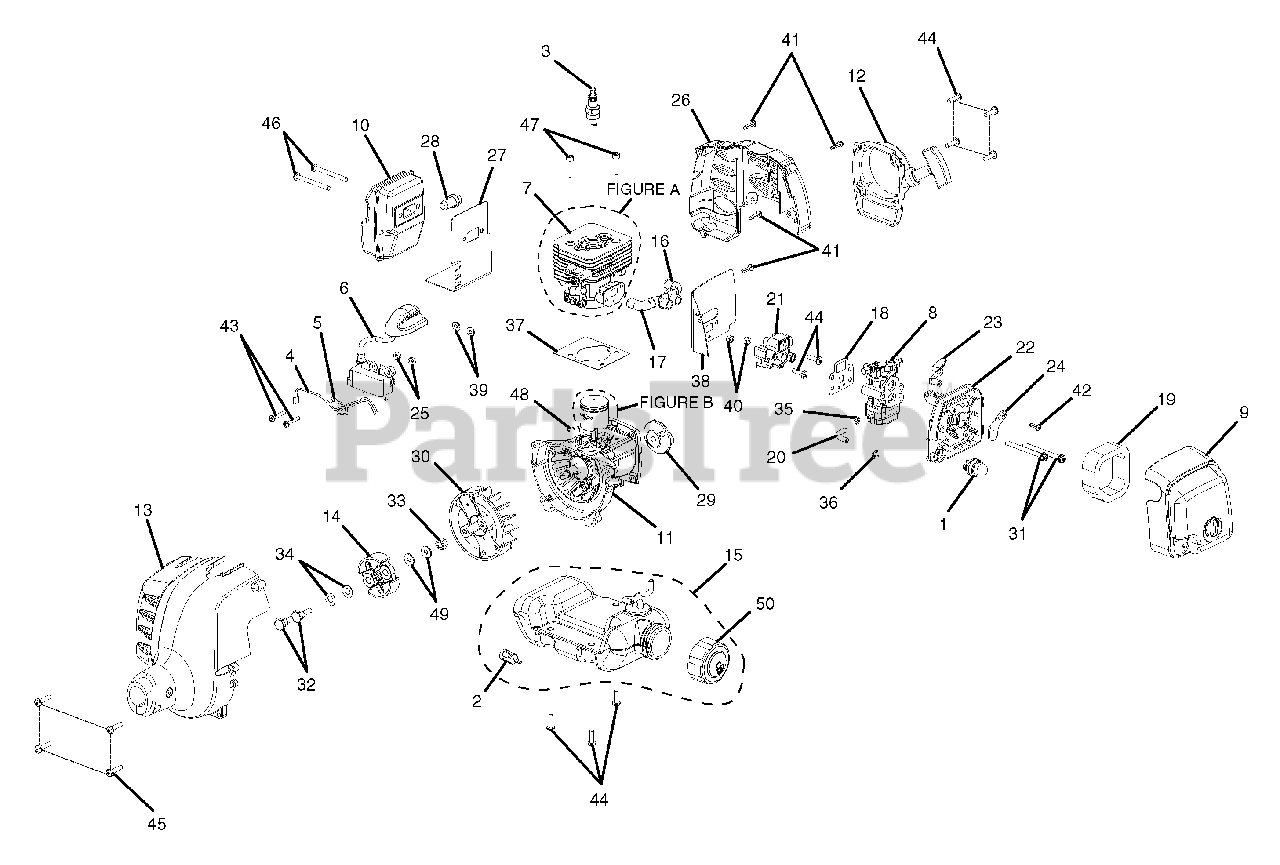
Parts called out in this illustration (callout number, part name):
1	Primer Assembly
2	Fuel Filter
3	Spark Plug
4	Lead Assembly, Black
5	Lead Assembly, Red
6	Coil, Boot,Assembly
7	Cylinder Assembly
8	Carburetor Assembly
9	Cover Assembly
10	Muffler Assembly
11	Crankcase Assembly
12	Starter Recoil Assembly
13	Front Housing Assembly
14	Clutch Assembly
15	Fuel Tank Assembly
16	Pipe, Air, Starter Side
17	Pipe, Air, Flywheel Side
18	Carburetor Gasket
20	Tubing, Plastic Rubber
21	Insulator, Heat Dam
22	Carburetor Plate
23	Choke Lever
24	Choke Plate
25	Ignition Coil Spacer
26	Engine Housing, Rear
27	Muffler Gasket
28	Spark Arrester
30	Rotor, Permanent Magnet
31	Screw (M5 x 0.8 x 60 mm, Slotted Recessed Pan HD. Machine)
32	Clutch Screw
33	Rotor Nut
34	Curved Washer
35	Hose Clip
36	Hose Clip
38	Insulator Gasket
39	Type A, Plain Washer (3/16 x 3/64, Steel, Zink
40	Nut, (M5 x .8 mm)Black Oxide
41	Screw (M4 x 1.75 x 16mm, Type TT, Slotted Recessed Pan HD.)
42	Screw (M4 x 1.75 x 12mm, Type TT, Slotted Recessed Pan HD.)
43	Screw (M4 x 0.7 x 22mm, Torx Recessed Pan HD., Machine)
44	Screw (M5 x 0.8 x 16mm, Torx Recessed Pan HD., Machine)
45	Screw (M5 x 0.8 x 20mm, Torx Recessed Pan HD., Machine)
46	Screw (M5 x 0.8 x 50mm, Torx Recessed Pan HD., Machine)
47	Screw (M5 x 0.8 x 22mm, Socket Head Cap, Black Oxide)
48	Woodruff Key(10 mm x 3.7 mm x 3 mm)
50	Fuel Cap
